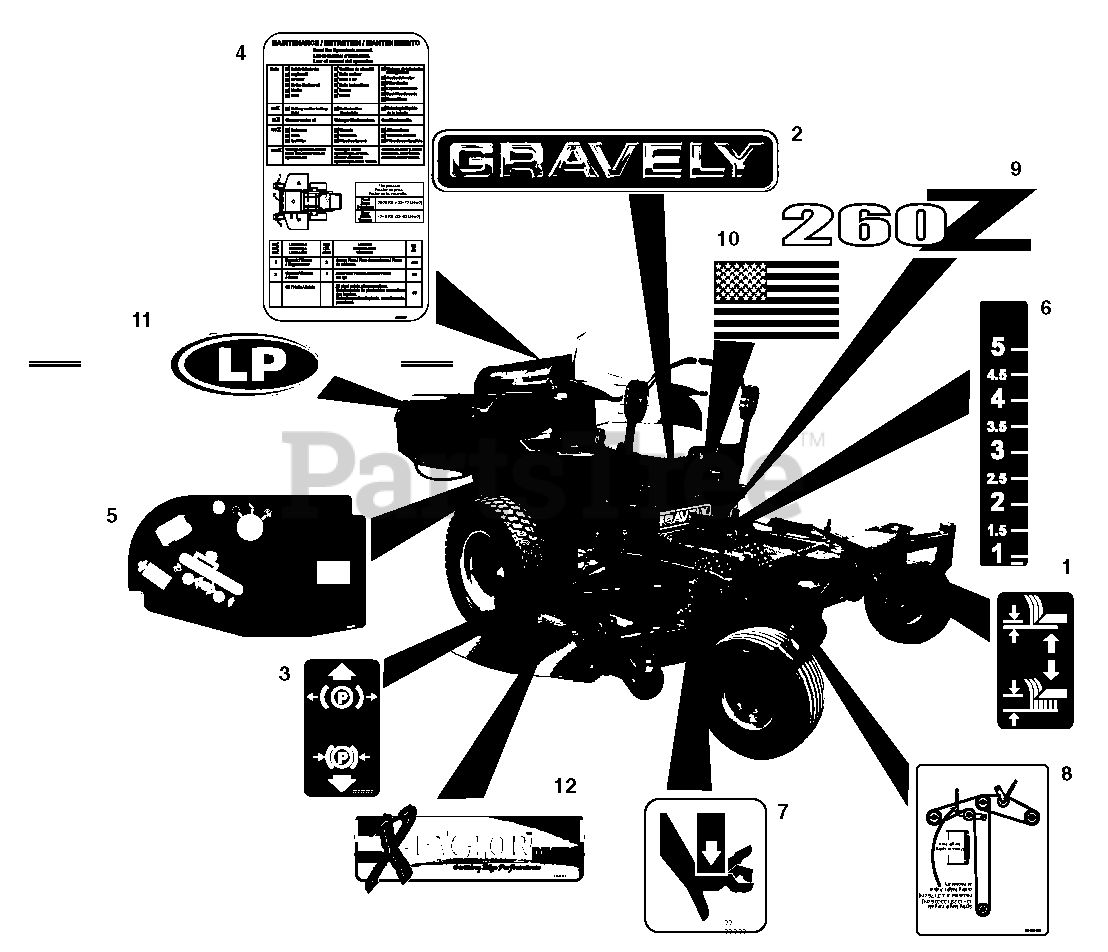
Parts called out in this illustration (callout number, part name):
1	Decal, Lift Lever
2	Decal, 15 in. Gravely Logo
3	Decal, Parking Brake Lever
4	Decal, Maintenance Instructions
5	Decal, Control Panel
6	Decal, Height of Cut
7	Decal, Pinch Point
8	Decal, Belt Diagram
9	Decal, PM-260Z
10	Decal, American Flag
11	Decal, LPG Logo
12	Decal, X-Factor Deck
